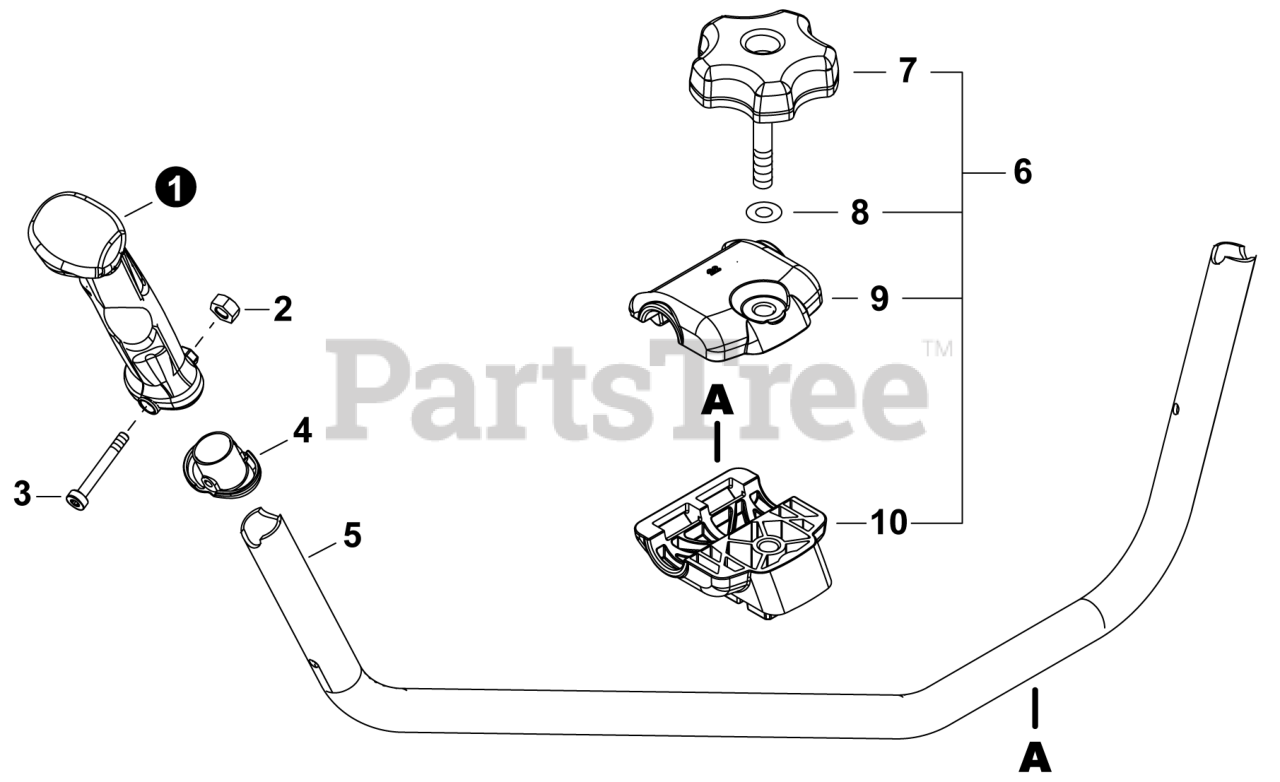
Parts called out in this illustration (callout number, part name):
1	GRIP, HANDLE
2	NUT, LOCK M5
3	BOLT, TORX 5×40
4	GUARD, HAND
5	U-HANDLE
6	BRACKET KIT, U-HANDLE
7	KNOB, SCREW M8
8	WASHER 8.2×17×1.6
9	BRACKET, HANDLE - UPPER
10	BRACKET, HANDLE - LOWER
